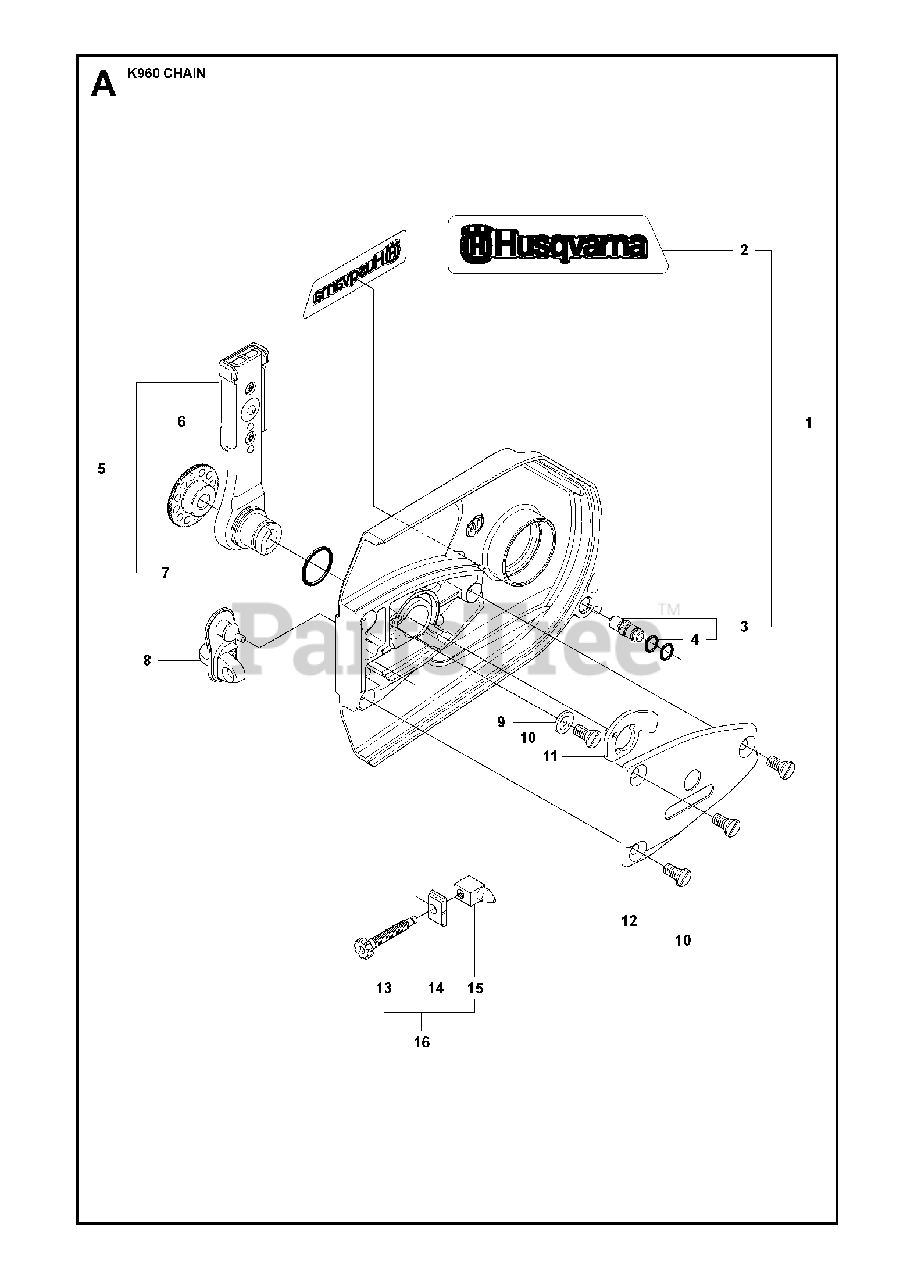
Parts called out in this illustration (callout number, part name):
1	CLUTCH COVERIncl. 2, 3
3	GUIDE PINIncl. 4
10	SCREW SLCSFM
16	SCREWIncl. 13, 14, 15
